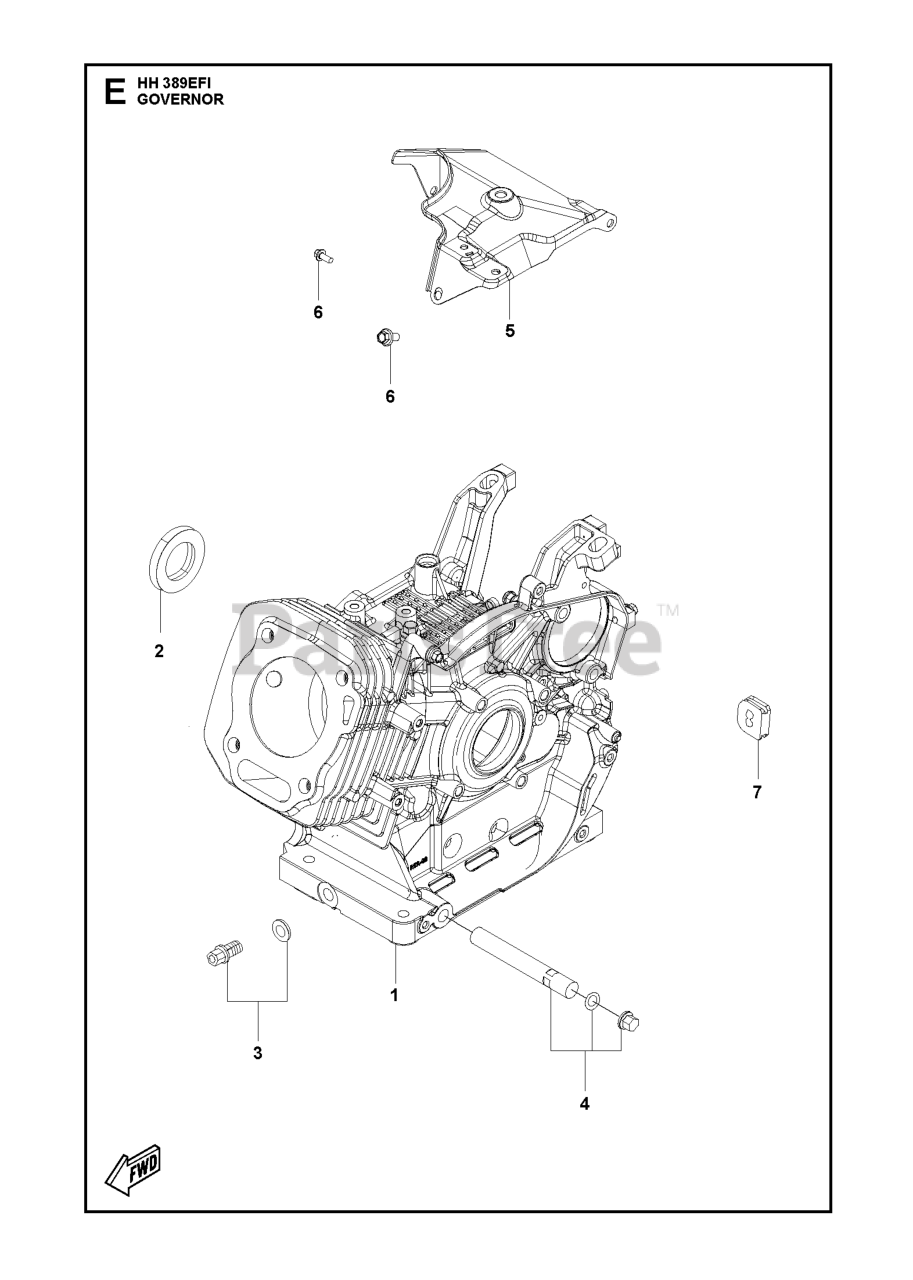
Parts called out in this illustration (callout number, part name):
2	SEAL OIL SEAL
5	PLATE THROTTLE BOTTOM PLATE
6	BOLT
7	PLUG RUBBER PLUG
